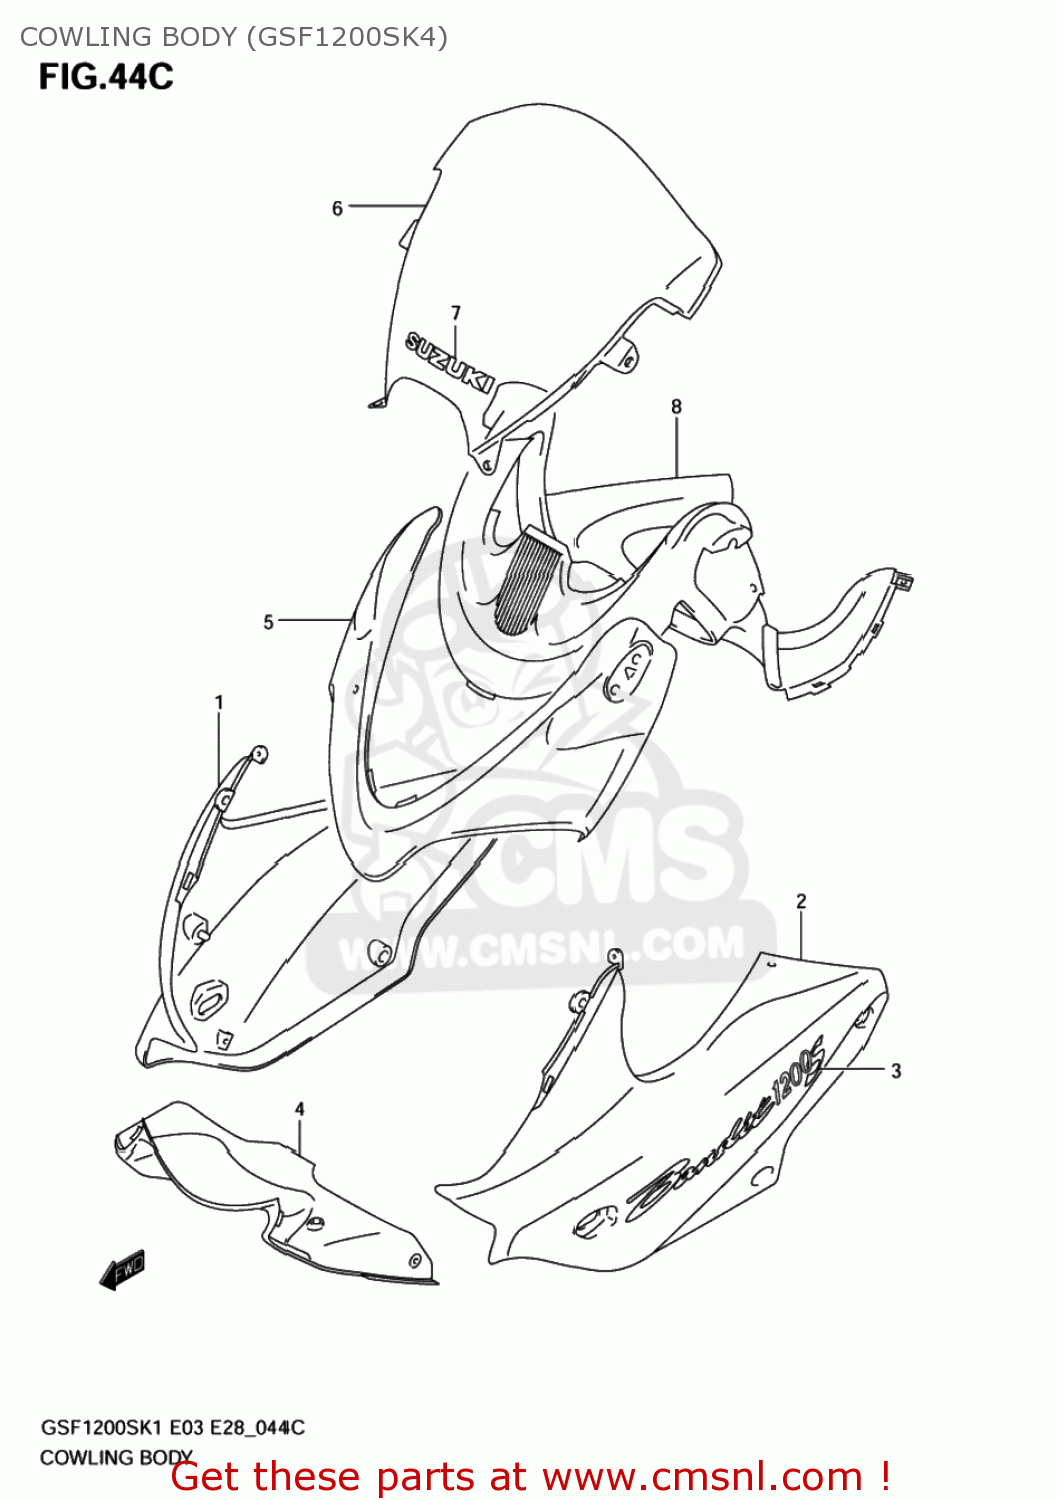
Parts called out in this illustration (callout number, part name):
1	COWLING ASSY,SIDE,R
2	COWLING ASSY,SIDE,L
3	EMBLEM,COWLING SIDE
4	COWLING,CTR(BLUE)
5	COWLING,FR
6	WINDSCREEN ASSY(SILVER)
7	EMBLEM,SUZUKI
8	PANEL,METER
